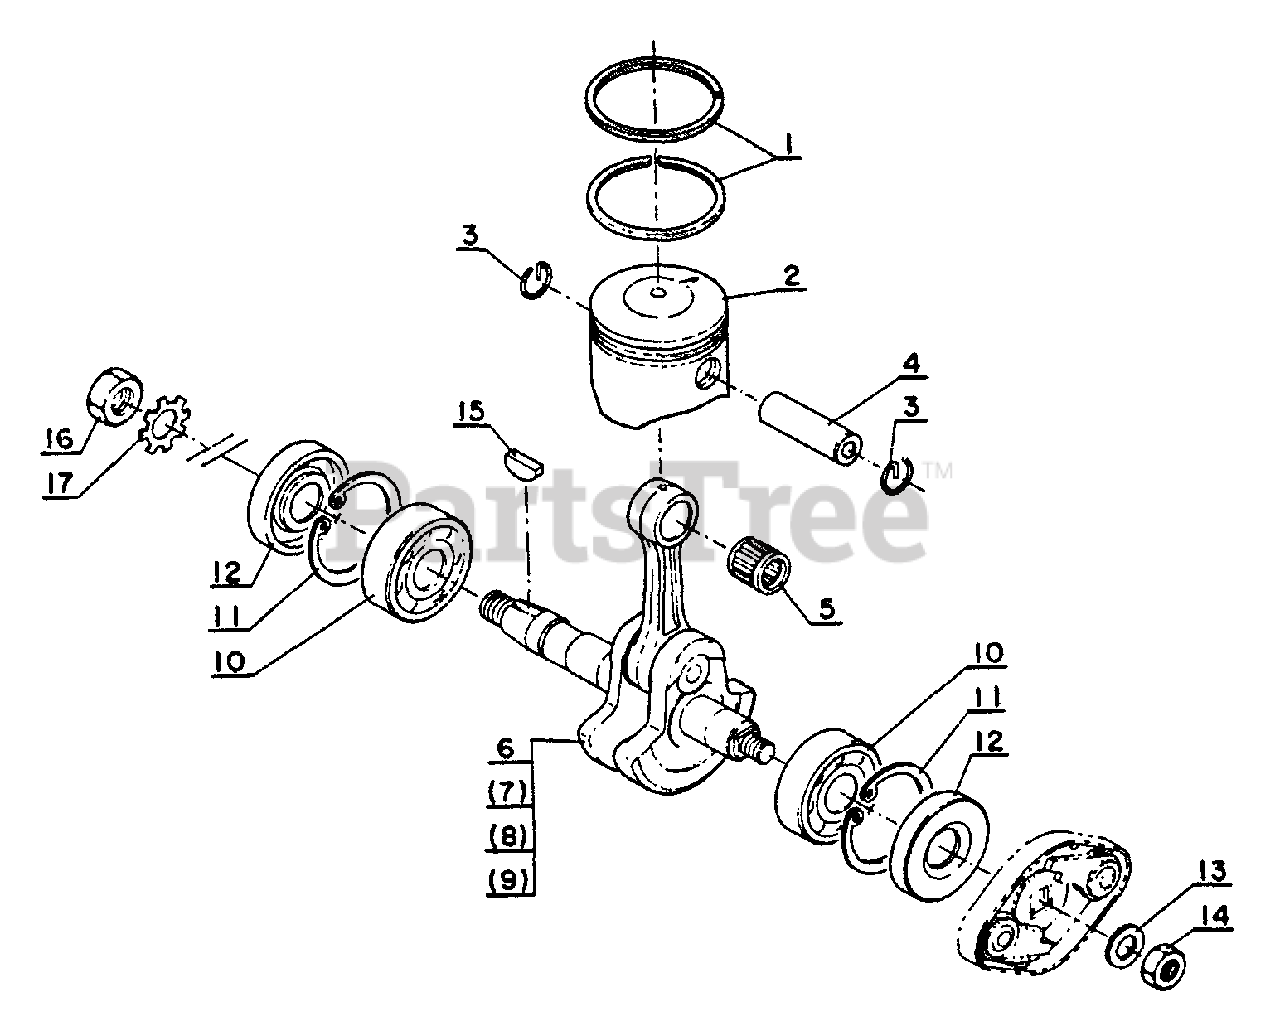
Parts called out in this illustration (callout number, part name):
1	RING, PISTON
2	PISTON
3	RING, RETAINING
4	PIN, PISTON
5	BEARING, NEEDLE
6	CRANKSHAFT ASSY
10	BEARING, BALL - 6201
11	RING, RETAINING - 32
12	SEAL, OIL
13	WASHER - 6
14	LOCKNUT - 6
17	LOCKWASHER - 8
